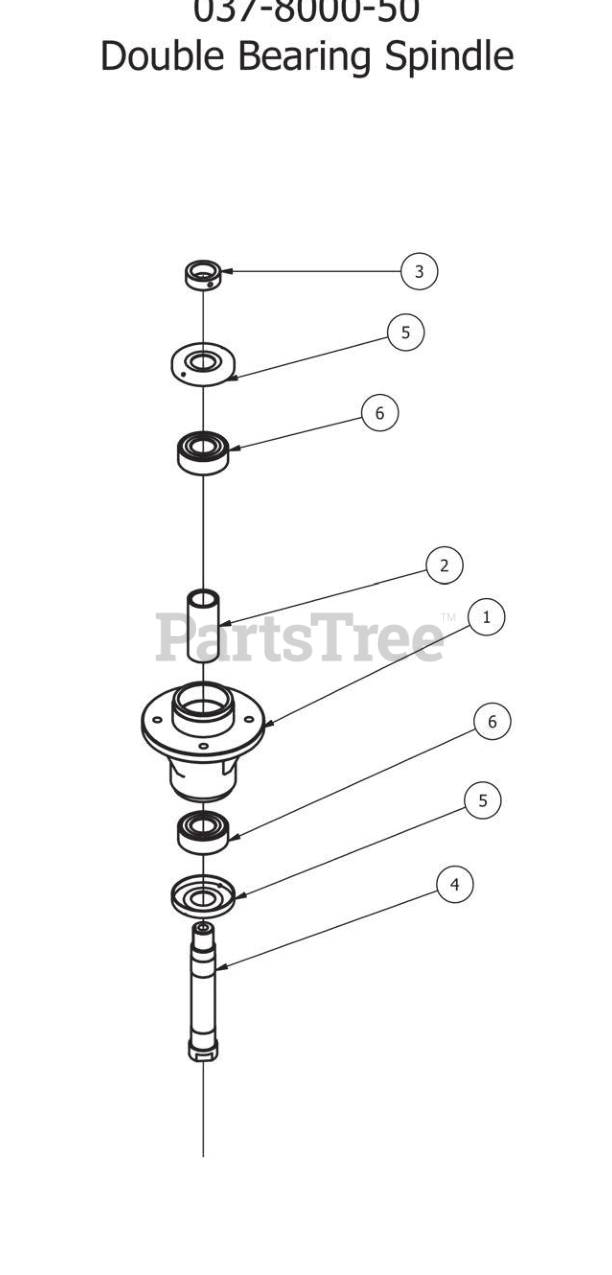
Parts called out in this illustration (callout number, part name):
1	Aluminum Spindle Housing
2	Tube Spacer Double Bearing Spindle
3	Collar Spacer - Top of Spindle
4	Short Spindle Shaft w/Locking
5	Dust Cover
6	Double Bearing for spindle
